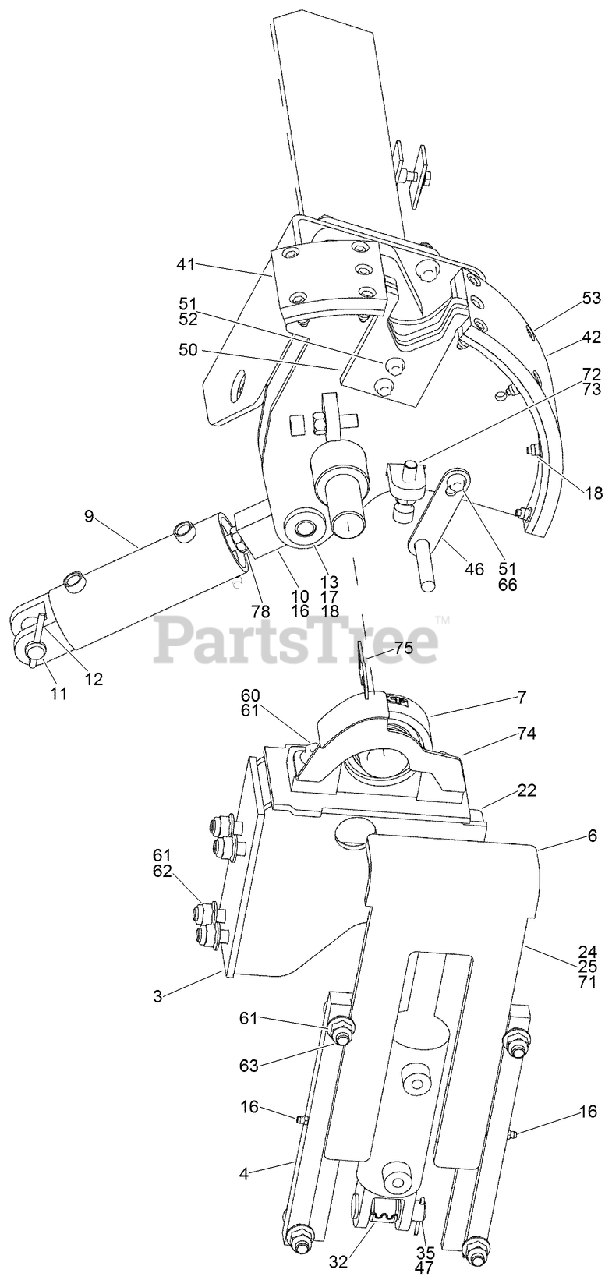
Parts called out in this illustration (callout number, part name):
3	ASSEMBLY - Bearing Mount
4	PLATE - Elevator Guide
6	ASSEMBLY - Elevator
7	BEARING-PILLOW
9	HYD CYLINDER ASM
10	EYE-ROD, CYLINDER
11	PIN-CLEVIS
12	PIN-COTTER
13	PIN-STRAIGHT
16	FITTING-Lube 1/4-28 Tpr SAE-LT .54 Long
17	SCREW, METRIC FLANGE w/BODY - M6 x 50
18	NUT, METRIC FLANGE PREVAILING - M6 Zinc
22	SWITCH-PROXIMITY
24	WASHER - 0.203 x 0.469 x 0.049 in CST ZND
25	NUT - Prev Trq # 10 GRB ZND Insert
32	BUSHING-SPRING
35	PIN-Cotter, 1/8 x 1-1/4 in ZN
41	PAD-WEAR, ROD LOADER
42	PAD-WEAR, ROD LOADER
46	FLAG-SENSOR
47	PIN-CLEVIS
50	PLATE-GUIDE, PIPE
51	NUT-TORQUE, PREVAILING
52	SCREW, METRIC FLANGE w/BODY - M8 x 40
53	SCREW, METRIC FLANGE w/BODY-M6 x 25
60	SCREW-HHF
61	NUT-HHF, LOCK
62	SCREW-HFH
63	SCREW, METRIC FLANGE FULL - M12 x 50
66	SCREW-HH
71	SCREW - Phd Sltd #10-24 x 1.00 CST ZND
72	SCREW - Soc Hd M12 x 50 Class 10.9 ZND
74	ASSEMBLY - Row Decal Mount
75	PLATE-POINTER
78	NUT - Jam, Hex, 5/8 - 18 NF
